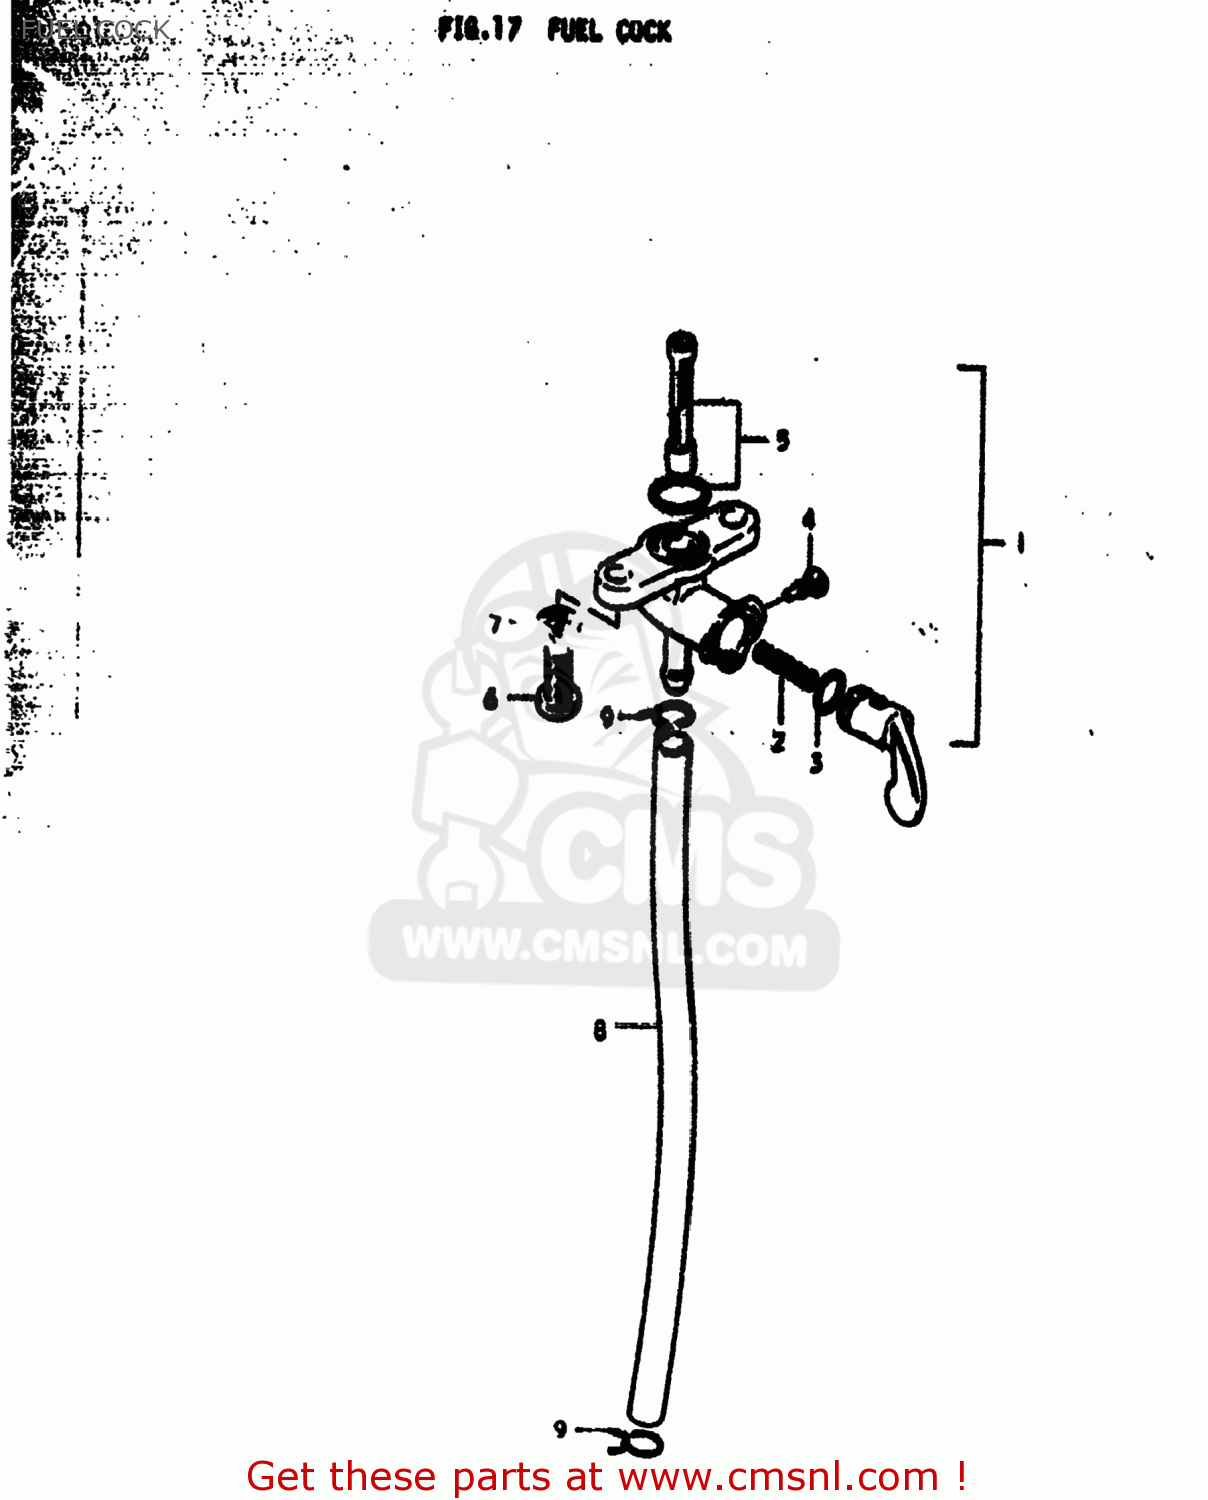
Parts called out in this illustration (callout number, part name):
1	COCK ASSEMBLY,FUEL
2	SPRING,FUEL COCK VALUE
3	O RING,LEVER
4	SCREW
5	FILTER SET FUEL
6	SCREW
7	LOCK WASHER
8	HOSE
9	CLIP
